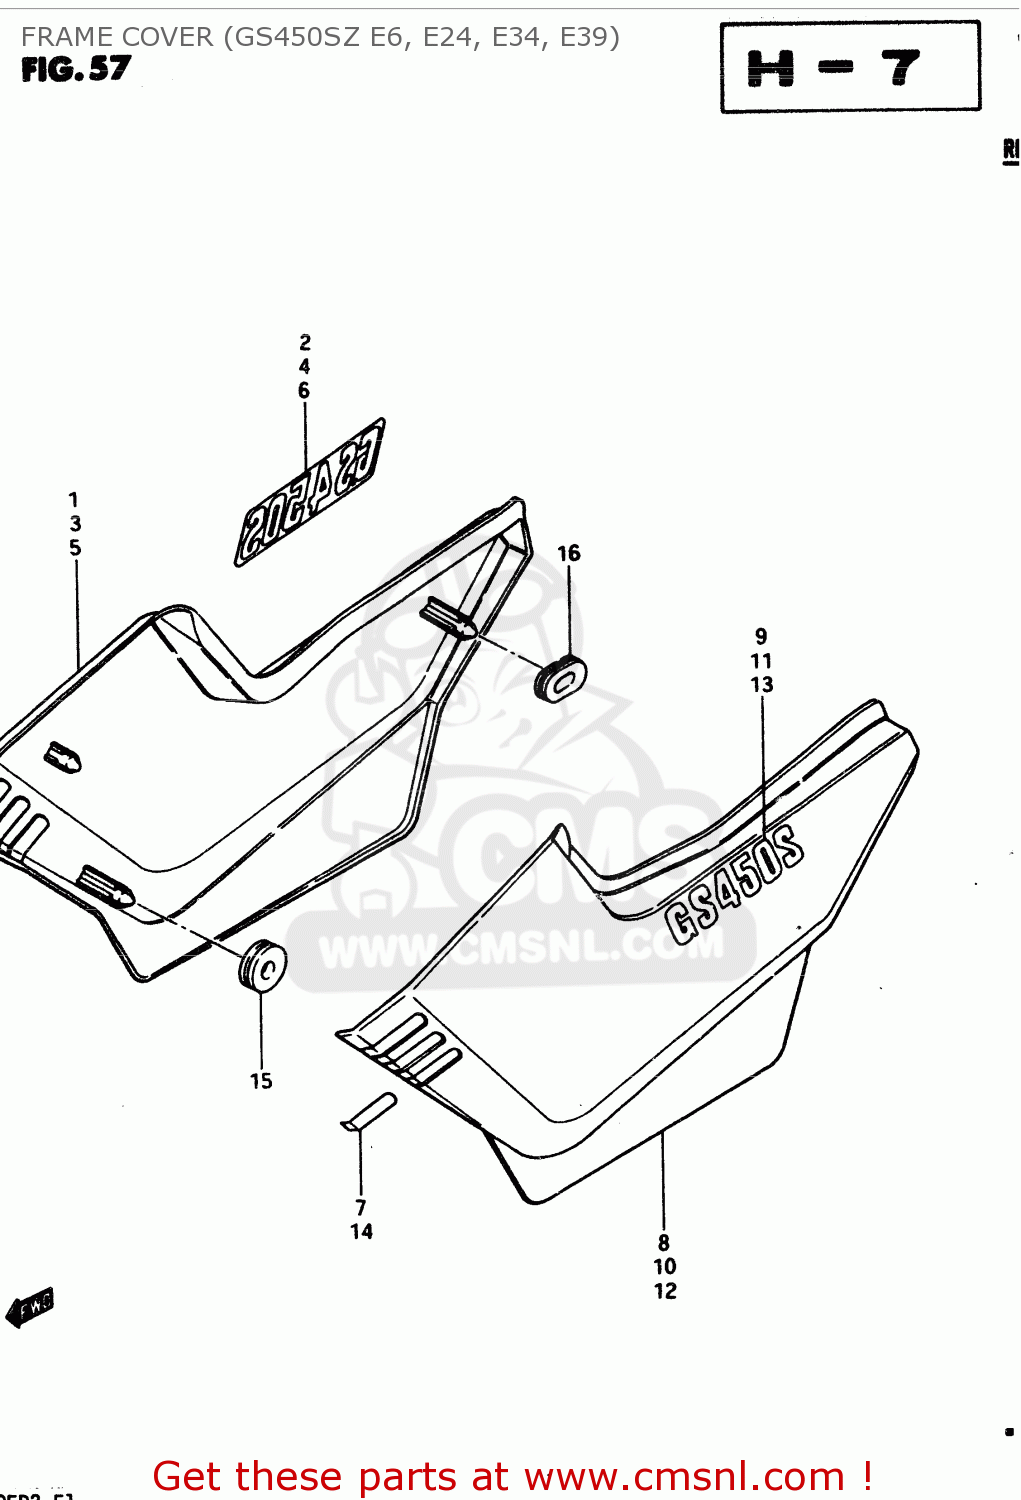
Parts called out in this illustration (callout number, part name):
1	COVER,FRAME,RIGHT
2	EMBLEM, LH
3	COVER, FRAME RH (SILVER)
4	EMBLEM, LH
5	COVER, FRAME RH (BLACK)
6	EMBLEM, LH
7	LABEL,FRAME COVER DENT
8	COVER,FRAME,LEFT
9	EMBLEM, LH
10	COVER, FRAME LH (SILVER)
11	EMBLEM, LH
12	COVER, FRAME LH (BLACK)
13	EMBLEM, LH
14	LABEL,FRAME COVER
15	CUSHION
16	CUSHION
